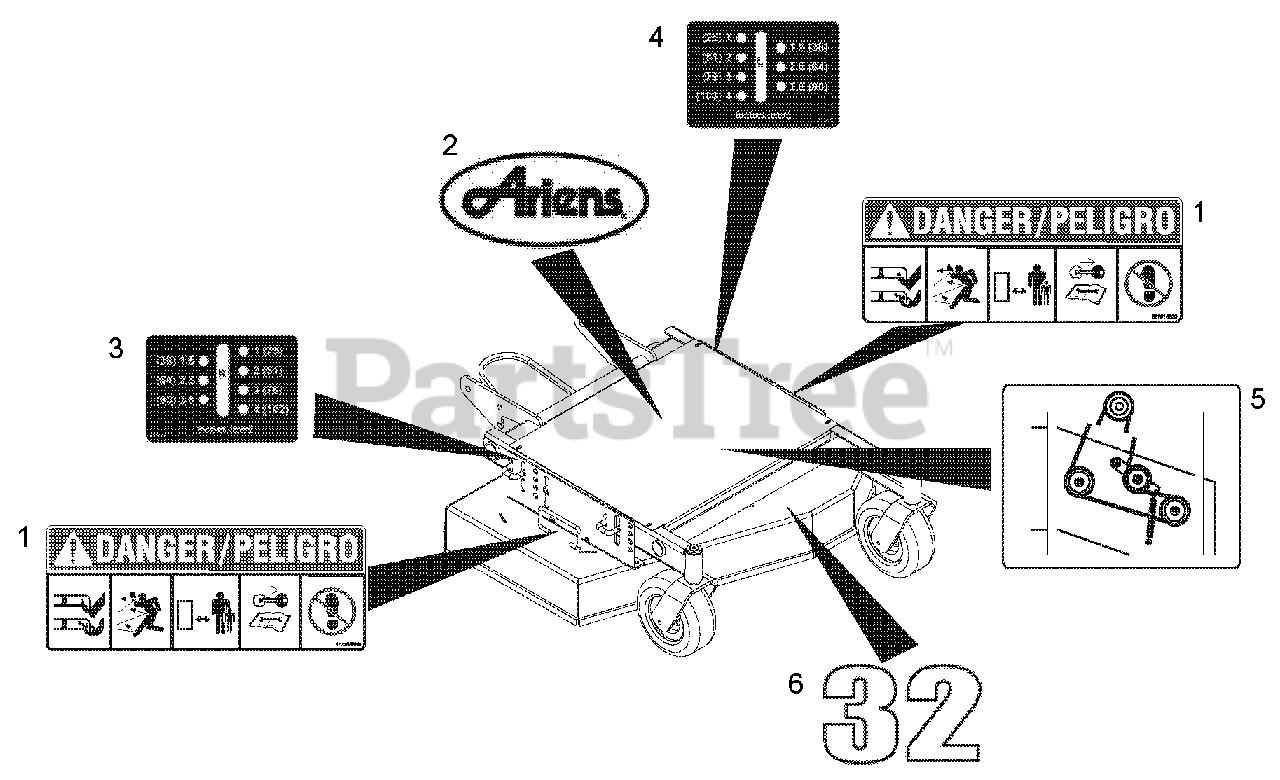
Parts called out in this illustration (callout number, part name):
1	DECAL, MOWER PAN DANGER
2	DECAL, ARIENS
3	DECAL-HEIGHT OF CUT-FIXED - RH
4	DECAL-HEIGHT OF CUT-FIXED - LH
5	DECAL-BELT DIAGRAM-2 SPINDLE
6	DECAL, 32
